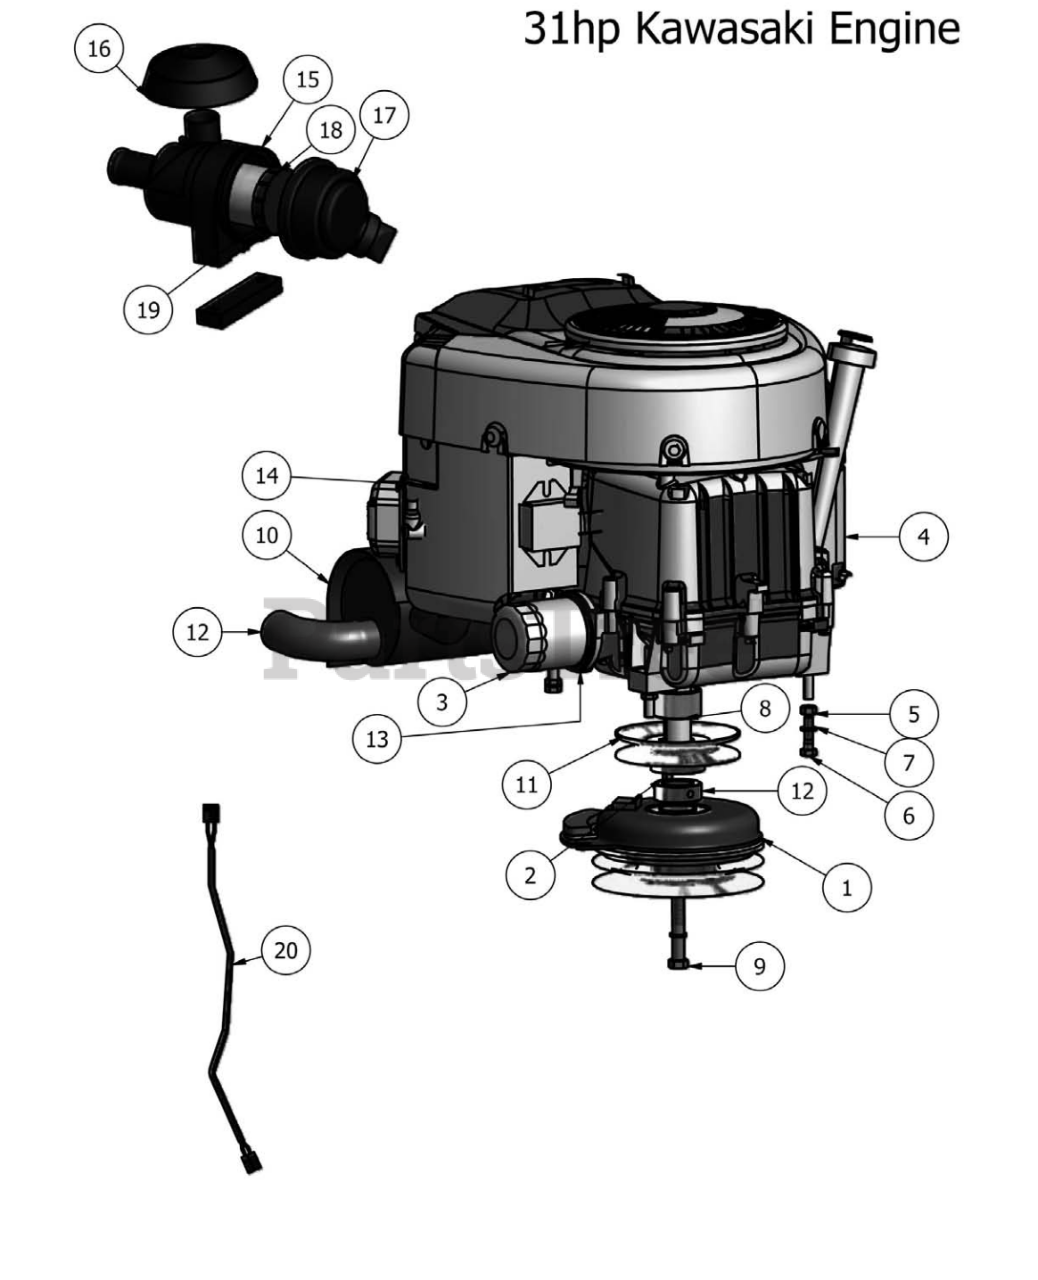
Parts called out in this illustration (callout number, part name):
2	1/4" x 1" Key
3	31 HP Oil Filter
4	31 HP Engine
5	5/16" Hex Nut
6	5/16" x 1 1/4" Hex Bolt
7	5/16" Lock Washer
8	1 1/8" Collar Spacer
9	7/16" x 2 1/2" Hex Bolt
10	31 HP Exhaust
11	4 3/4" Motor Pulley
12	1 1/8" Pulley Spacer
13	Oil Drain Valve
14	Fuel Filter
15	31hp Kawasaki Complete Canister
16	Rain Cap 31hp Kawasaki
17	Filter End Cap
18	Air Filter-Outer
19	Air Filter-Inner
20	Clutch Pigtail
